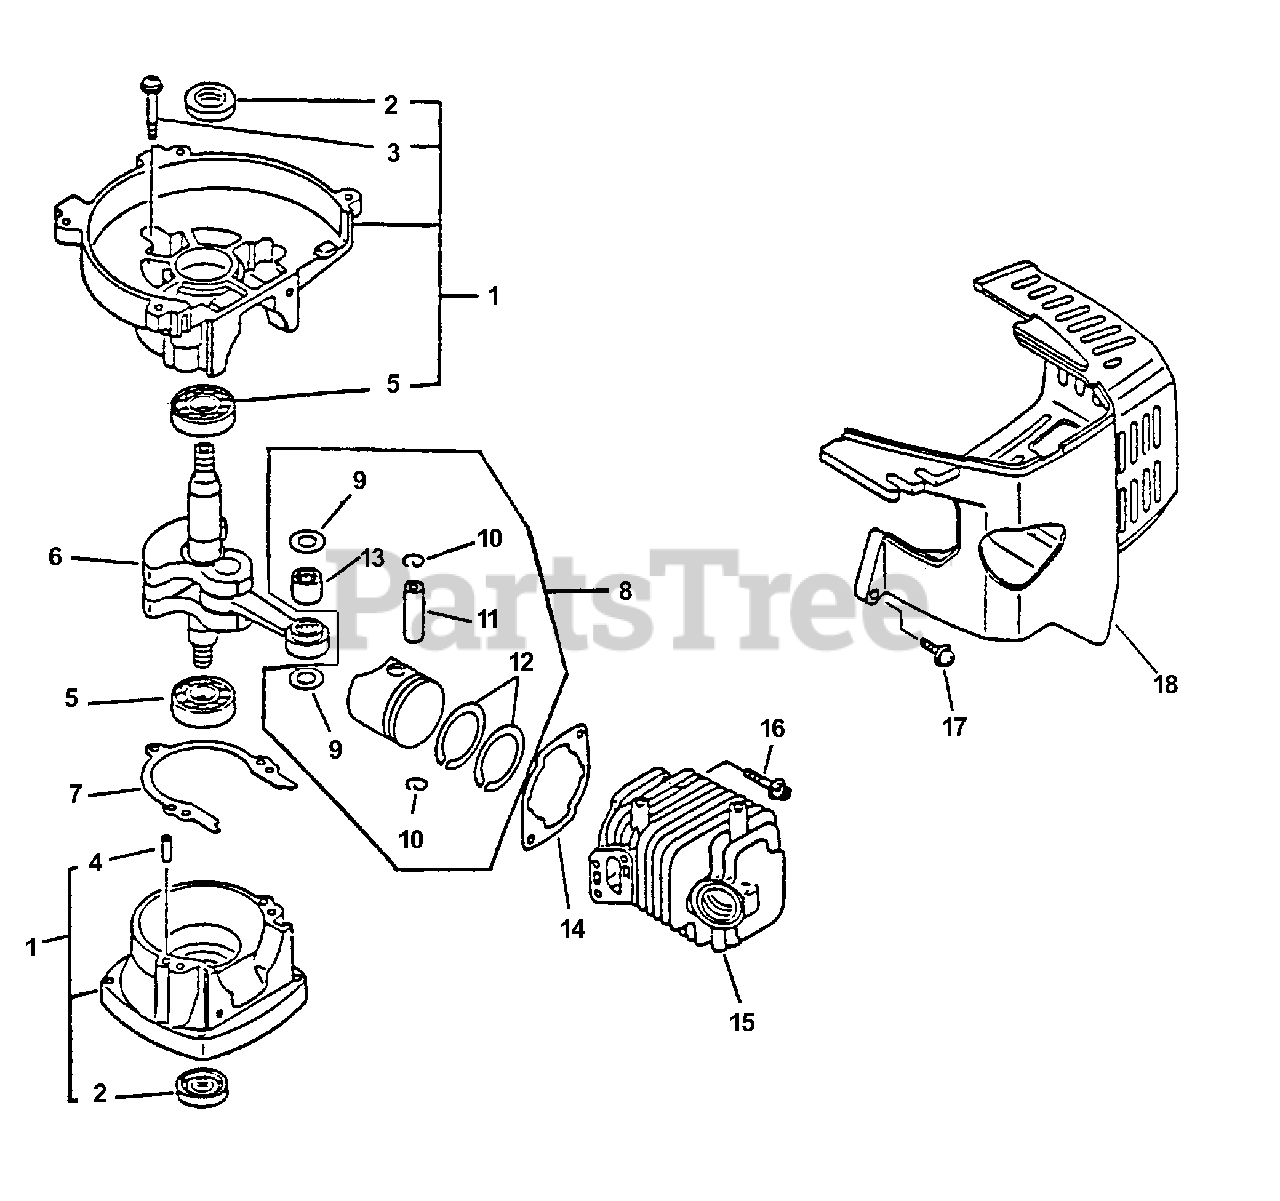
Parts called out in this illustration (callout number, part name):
1	CRANKCASE KIT
2	SEAL, OIL 12
3	BOLT 5×28
4	PIN, LOCATING 4
5	BEARING, BALL - 6201 C3
6	CRANKSHAFT ASSY
7	GASKET, CRANKCASE
8	PISTON KIT
9	WASHER, THRUST
10	RING, SNAP
11	PIN, PISTON 8
12	RING, PISTON
13	BEARING, NEEDLE
14	GASKET, CYLINDER
15	CYLINDER
16	BOLT 5×22
17	SCREW 4×22
18	COVER, CYLINDER
